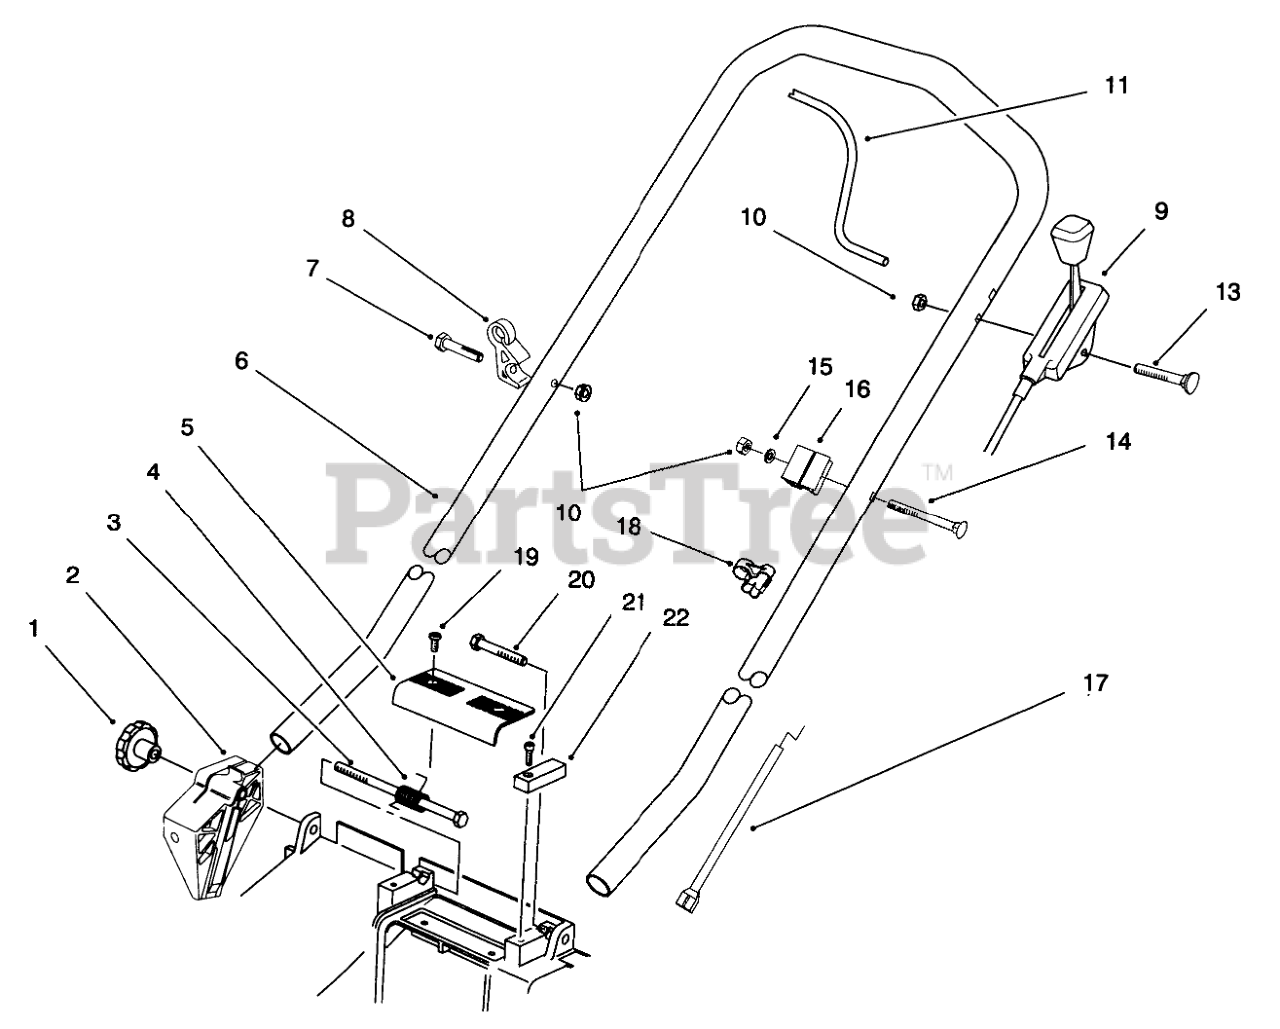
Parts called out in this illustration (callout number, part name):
2	Mount-Handle R.H.
3	BOLT-LONG
4	SPRING-DOOR
5	GRIP-UPPER
6	HANDLE
7	.250-20X1.625 HH SCREW
8	GUIDE - ROPE
9	CONTROL - THROTTLE
10	NUT-LOCK, NI
11	Bail-Brake
13	SCREW-HH
14	SCREW-HANDLE
15	WASHER-FLAT
16	SUPPORT-CABLE
17	CABLE - BRAKE
18	CLAMP-CABLE
19	SCREW-PPH, PLASTITE
20	BOLT-SHORT
21	SCREW-CAP, HINGE
22	CAP-BOLT
